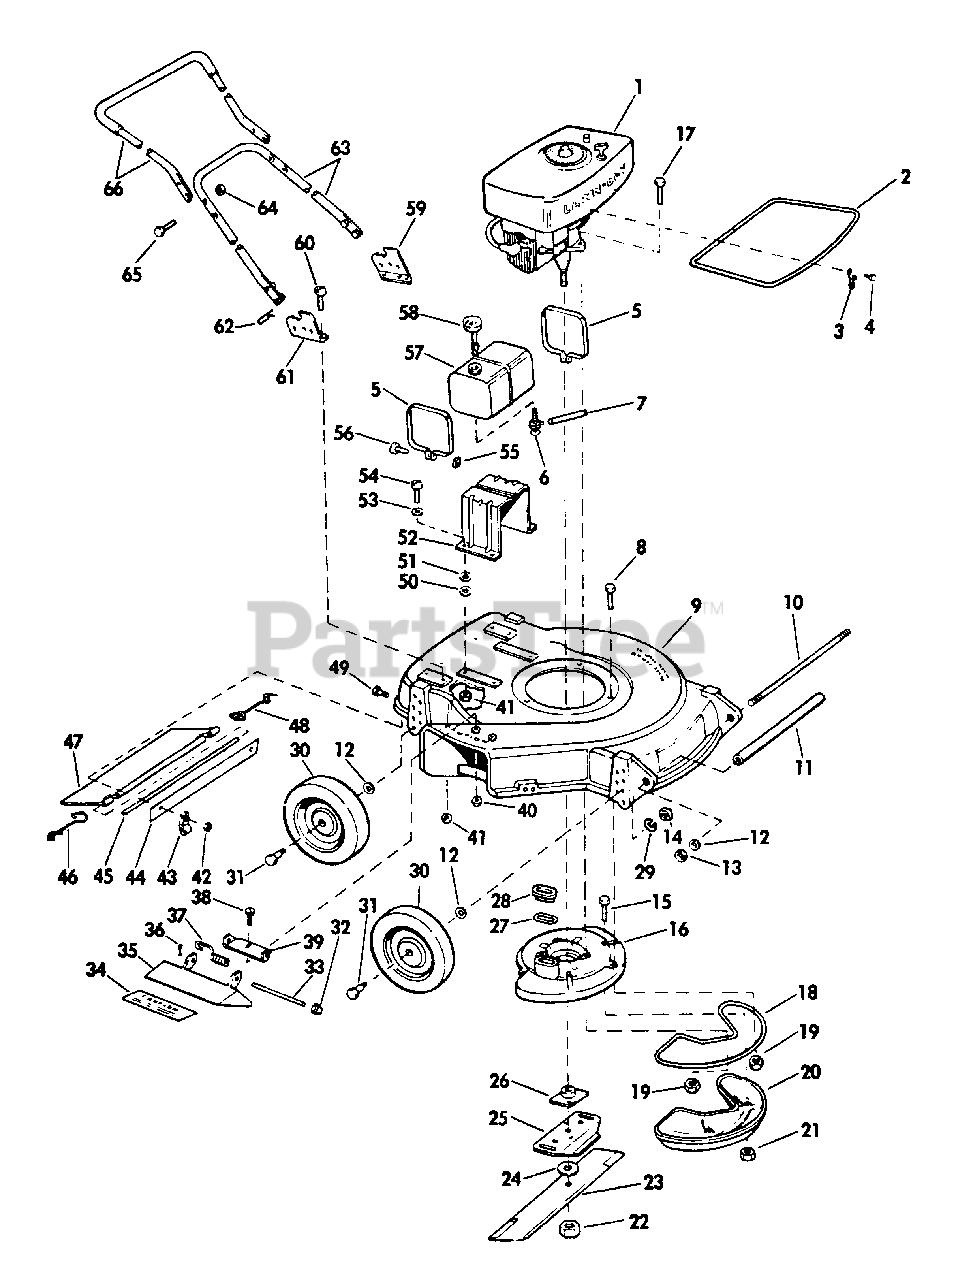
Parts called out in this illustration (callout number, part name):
1	See Note #2 at bottom of this page.
2	Loop-Arm. Plate Protective Wire
3	Spring-Wire Loop Mounting
5	Strap-Gas Tank
6	Shut-Off Valve & Screen
7	Gas Line
8	Screw-Muffler Plate to Housing
9	Housing & Bar Assembly-21"
10	Rod-Bumper
14	Nut-Square
16	Muffler Plate Assembly
18	Gasket-Muffler
19	Nut-Nylok
20	Muffler
22	Blade Nut
23	Blade-21"
24	Washer-Blade
25	Stiffener-Blade
26	Collar & Plate
27	Gasket-Exhaust
28	Sleeve-Muffler Gasket
29	Lockwasher
30	Wheel & Tire Assy.-8"
31	Wheel Bolt-Shoulder
32	Push Nut
35	Deflector
36	Cotter Pin
44	Extension
46	Spring-R.H.
48	Spring-L.H.
51	Grommet
52	Bracket-Gas Tank
55	Nut-Plain Square
56	Screw-Strap to Bracket
57	Gas Tank Assy.
58	Fuel Gauge Assy.
59	Handle Bracket, Left
60	Screw-Slotted
61	Handle Bracket, Right
62	Hair Pin
63	Handle Bottom & Pin Assy.
64	Nut Stop-Handle
65	Screw-Handle
66	Top Handle Section & Grip Assy.
